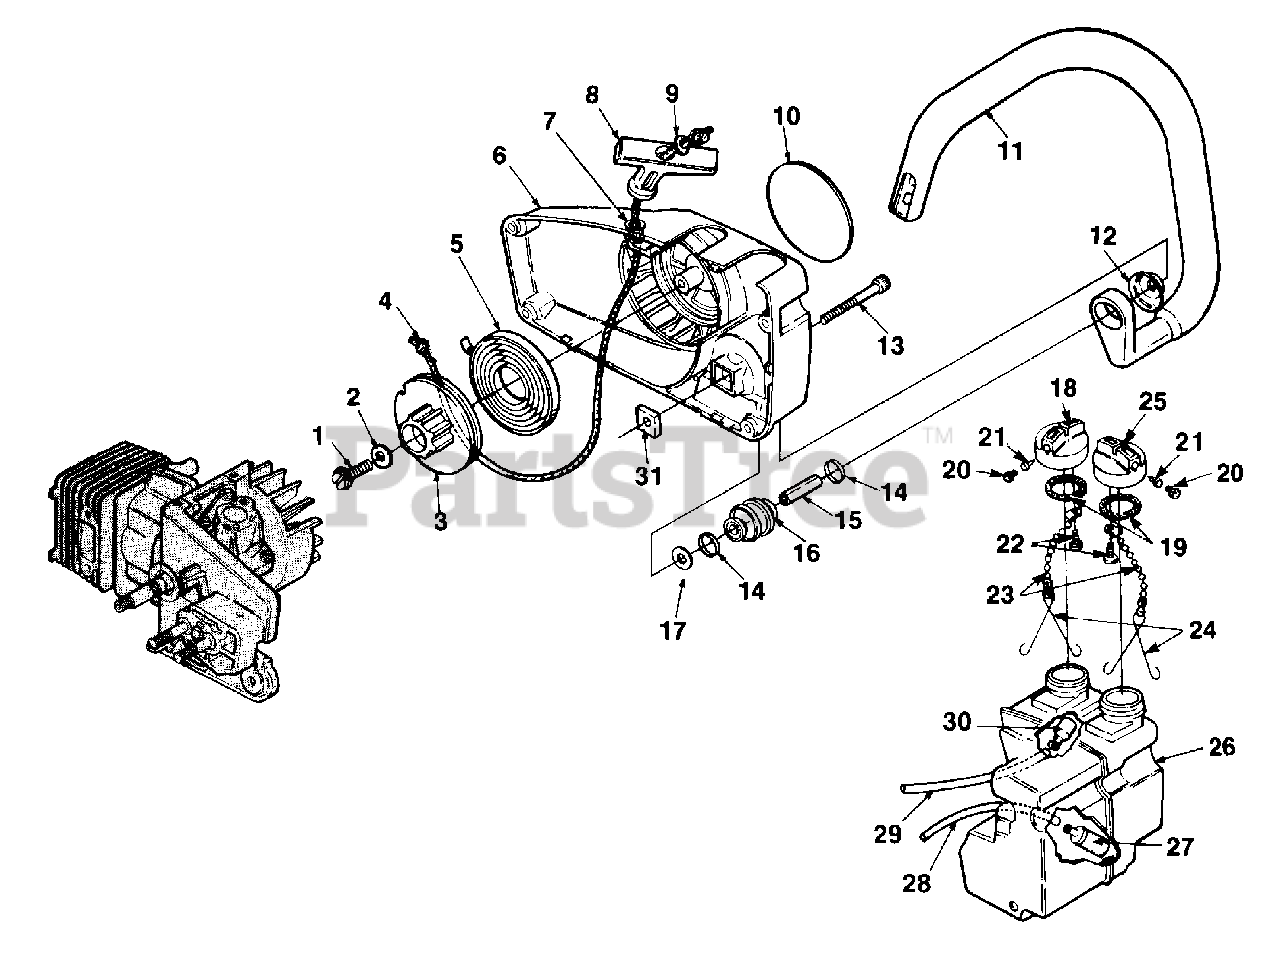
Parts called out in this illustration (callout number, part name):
1	SCREW- #10 x 3/4
2	WASHER- Retainer
3	PULLEY- Starter
4	ROPE- Starter #3 1/2, 46"
5	SPRING- Rewind
6	HOUSING- Starter
7	BUSHING- Starter
8	GRIP- Starter rope
9	WASHER- Flat #8
10	DECAL- "240"
11	HANDLE BAR
12	WASHER- Vibration isolator
13	SCREW- Soc. hd. (10-24 x 5/8)
14	RING- Vibration isolator
16	ISOLATOR
17	WASHER- Flat
18	CAP-Oil
19	GASKET- Filler cap
20	FILTER- Filler cap
21	VALVE- Check
22	SCREW- Pan hd.
23	BEAD- Chain
24	KEEPER- Cap
25	CAP- Fuel
26	TANK- Fuel & Oil
27	FILTER Fuel
28	TUBING Fuel 6 1/2"
29	TUBING- Oil outlet 4 1/2
30	FILTER- Oil
31	NUT- Square 10-24
